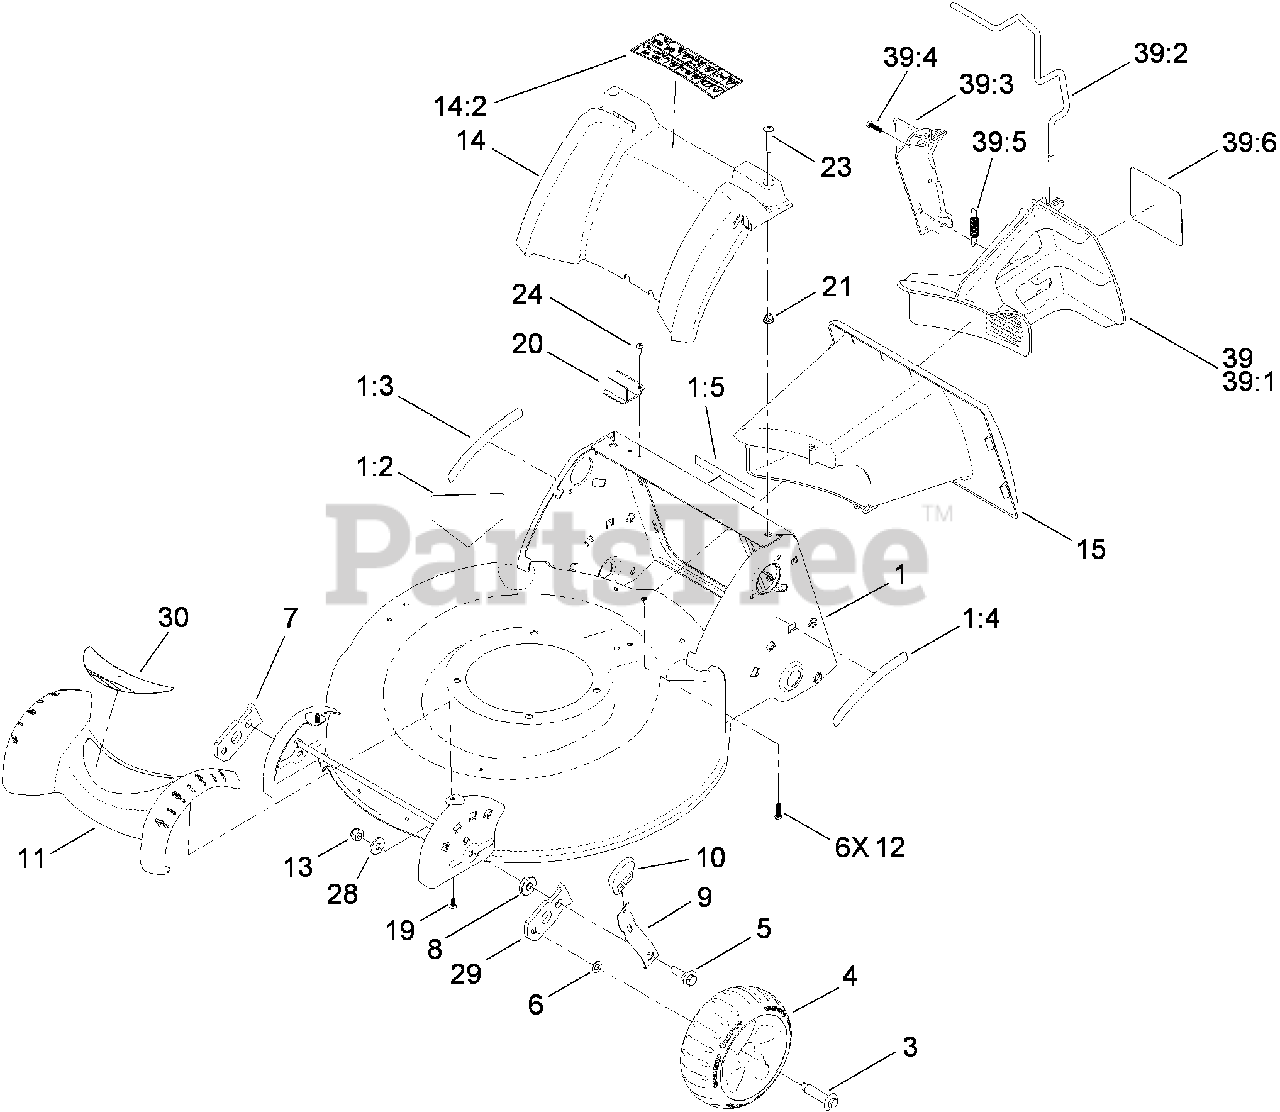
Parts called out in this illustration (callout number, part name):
1	HOUSING ASM
1:2	DECAL-DANGER
1:3	DECAL-HOC, RH
1:4	DECAL-HOC, LH
1:5	DECAL-SAFETY
3	BOLT-SHOULDER
4	7 INCH FRONT WHEEL ASM
5	BOLT-SHOULDER
7	ARM-PIVOT, RH
9	ARM-SPRING
11	COVER-FRONT
12	SCREW-PLASTITE
13	NUT-LOCK, NI
14	COVER-REAR
14:2	DECAL-WARNING
19	SCREW-PLASTITE
20	MODULE-SWITCH
21	NUT-CLIP
23	SCREW-PTH
24	SCREW-THREAD FORMING
28	WASHER-HARDENED
29	ARM-PIVOT, LH
39	MULCH PLUG ASM
39:1	PLUG-MULCH, LH
39:2	LATCH-PLUG, MULCH
39:3	PLUG-MULCH, RH
39:4	SCREW-PLASTITE
39:5	SPRING-EXTENSION
39:6	DECAL-PLUG, MULCH
